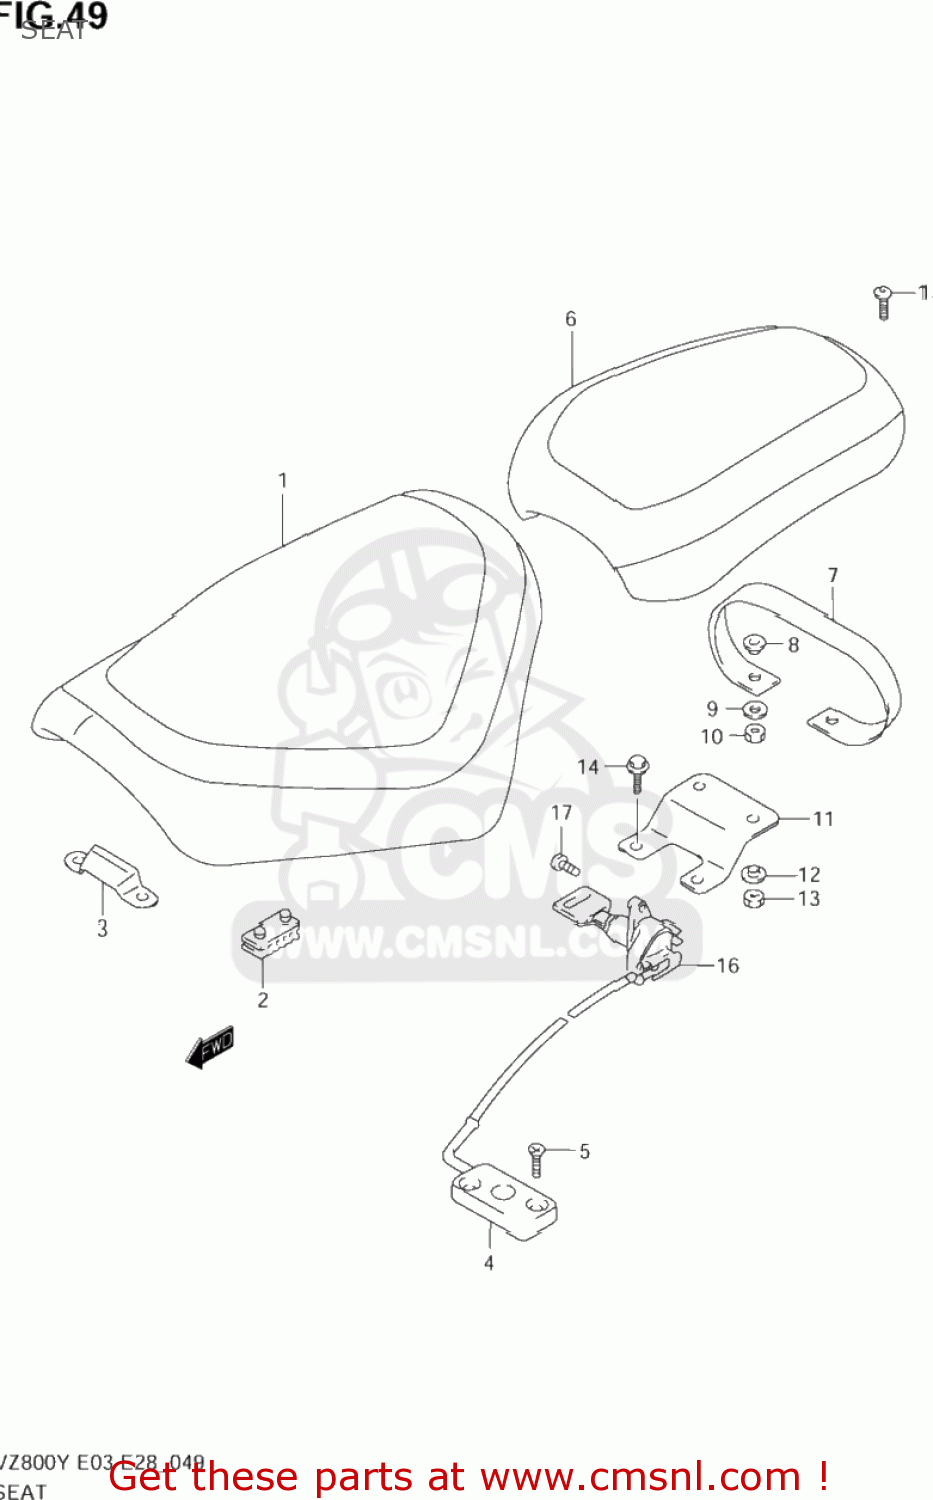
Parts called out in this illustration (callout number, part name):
1	SEAT ASSY
2	CUSHION,SEAT(40X20X15)
3	PLATE,FR SEAT HOOK
4	BRACKET,SEAT SUPPORT FR
5	SCREW
6	SEAT ASSY,PILLION
7	BAND ASSY,SEAT
8	WASHER
9	WASHER(6.5X18X1.6)
10	NUT
11	PLATE,PILLION SEAT
12	WASHER
13	NUT
14	BOLT
15	BOLT(8X16)
16	LOCK SET,SEAT
17	SCREW(6X14)
